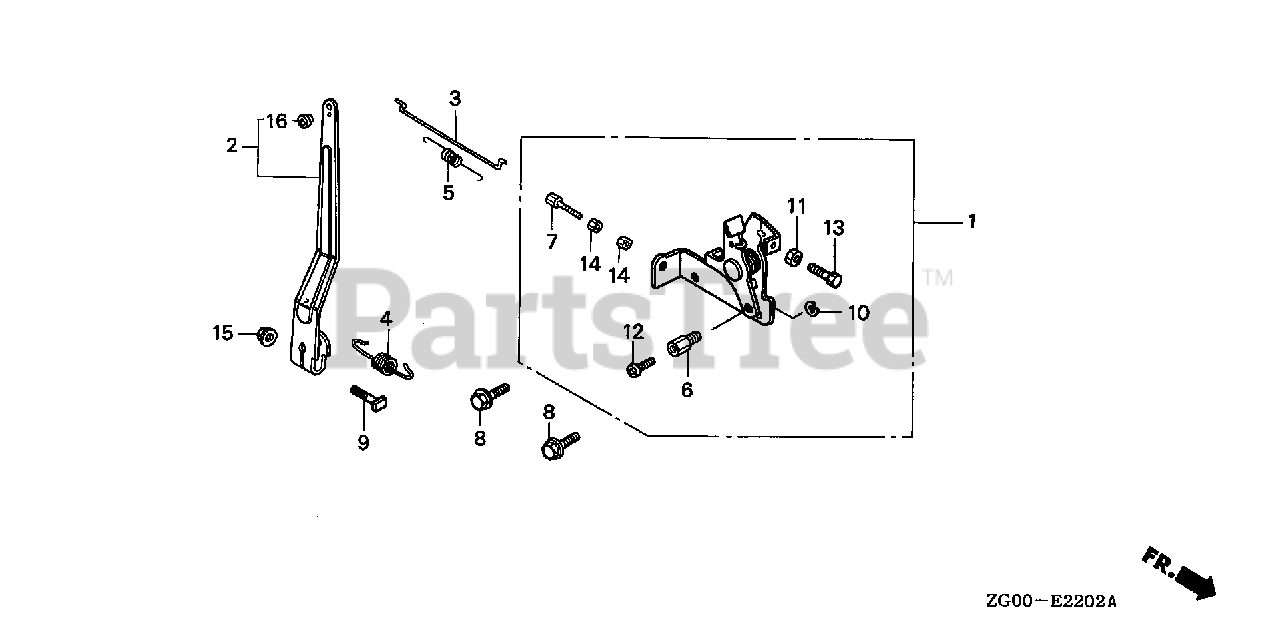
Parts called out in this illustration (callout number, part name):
1	CONTROL ASSY.
2	ARM, GOVERNOR
3	ROD, GOVERNOR
4	SPRING, GOVERNOR
5	SPRING, THROTTLE RETURN
6	HOLDER, WIRE
7	BOLT, CABLE ADJUSTING (6X34)
8	BOLT, FLANGE (6X12) (CT200)
9	BOLT, GOVERNOR ARM
10	CIRCLIP (5MM)
11	NUT, HEX. (5MM)
12	SCREW, PAN (4X6)
13	BOLT, HEX. (5X20)
14	NUT, HEX. (6MM)
15	NUT, FLANGE (6MM)
16	COLLAR, LEVER
